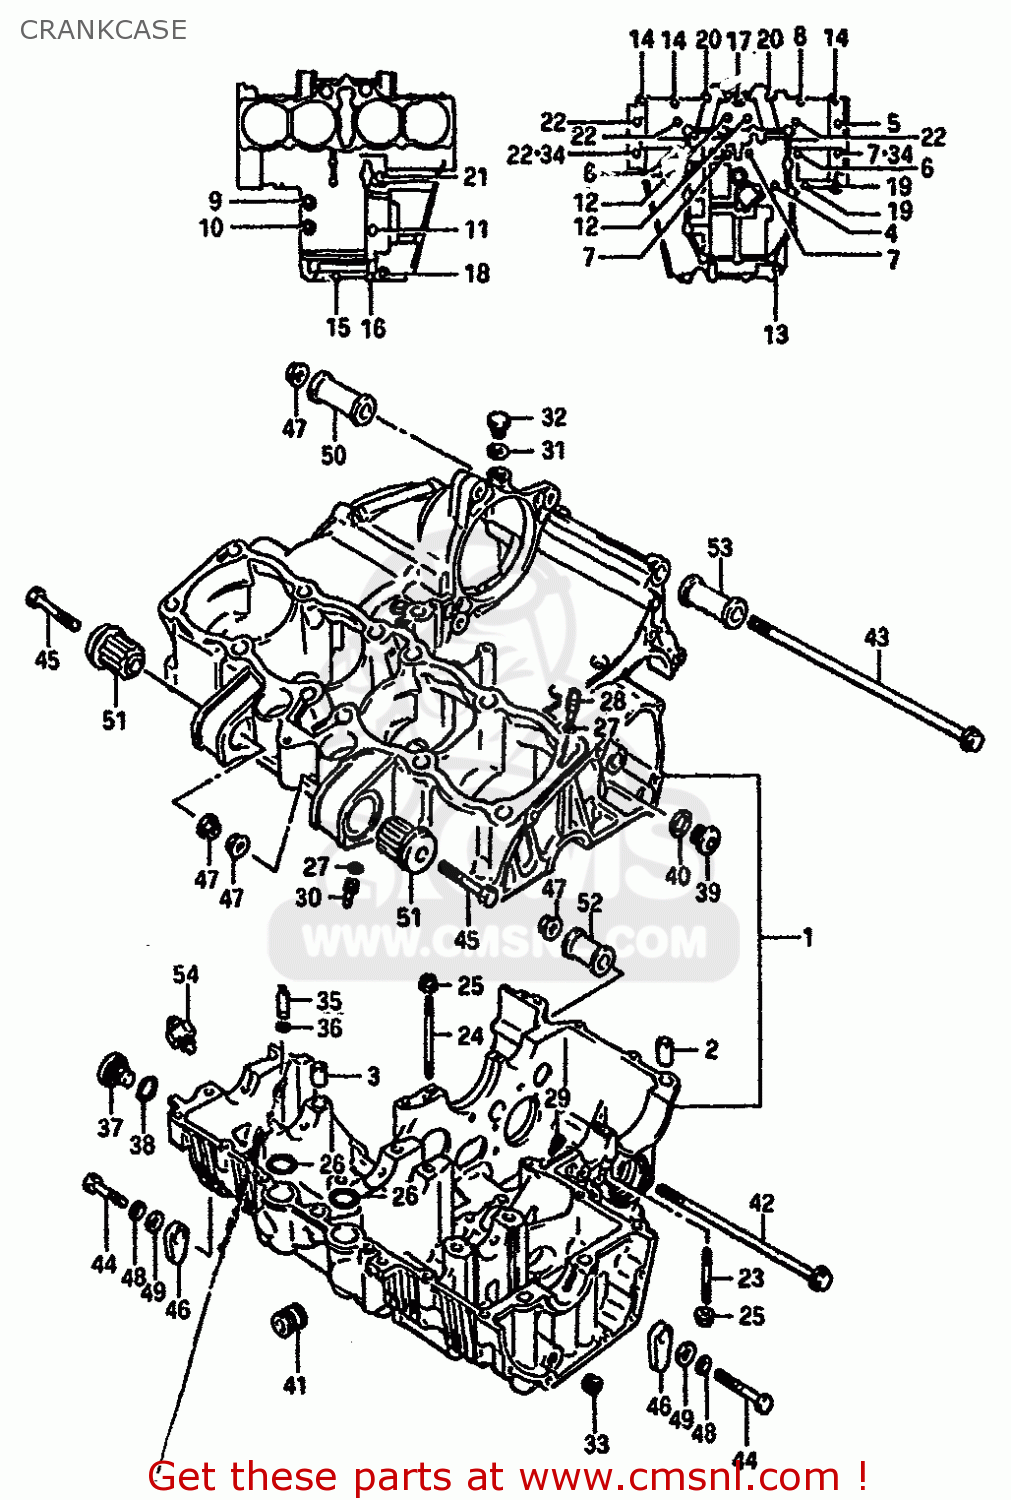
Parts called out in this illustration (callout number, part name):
1	CRANKCASE SET
2	PIN(10.4X13X22)
3	PIN (11X20)(SUS)
4	BOLT(6X105)
5	BOLT(8X105)
6	BOLT(8X125)
7	BOLT(8X115)
8	BOLT 6X35
9	BOLT
10	BOLT
11	BOLT
12	BOLT
13	BOLT 8X60
14	BOLT 6X35
15	BOLT
16	BOLT
17	BOLT 6X50
18	BOLT ,6X60
19	BOLT
20	BOLT
21	BOLT
22	BOLT(8X95)
23	STUD BOLT
24	STUD BOLT
25	NUT
26	O RING(D:2.5,ID:21)
27	O RING(D:1.2,ID:4)
28	JET,AIR
29	JET
30	JET,OIL GALLERY
31	GASKET(12.1X16.2X3.7) (NAS)
32	PLUG(12X9)
33	PLUG(1/4PT,H:7.5)
34	GASKET(8.5X17X2.3) (NAS)
35	VALVE ASSEMBLY,PISTON OIL
36	O RING(D:1.2,ID:4.7)
37	PLUG
38	O RING(D:2.4,ID:16.8)
39	PLUG
40	GASKET(14X19.2X2) (NAS)
41	UNION,OIL STAND
42	BOLT(10X180)
43	BOLT(10X255)
44	BOLT 10X55
45	BOLT 10X55
46	NUT
47	NUT
48	WASHER,LOCK,10
49	WASHER
50	SPACER,ENGINE MOUNT
51	BUSH,ENGINE MOUNTING
52	SPACER,ENGINE MOUNT
53	SPACER
54	SWITCH ASSEMBLY
